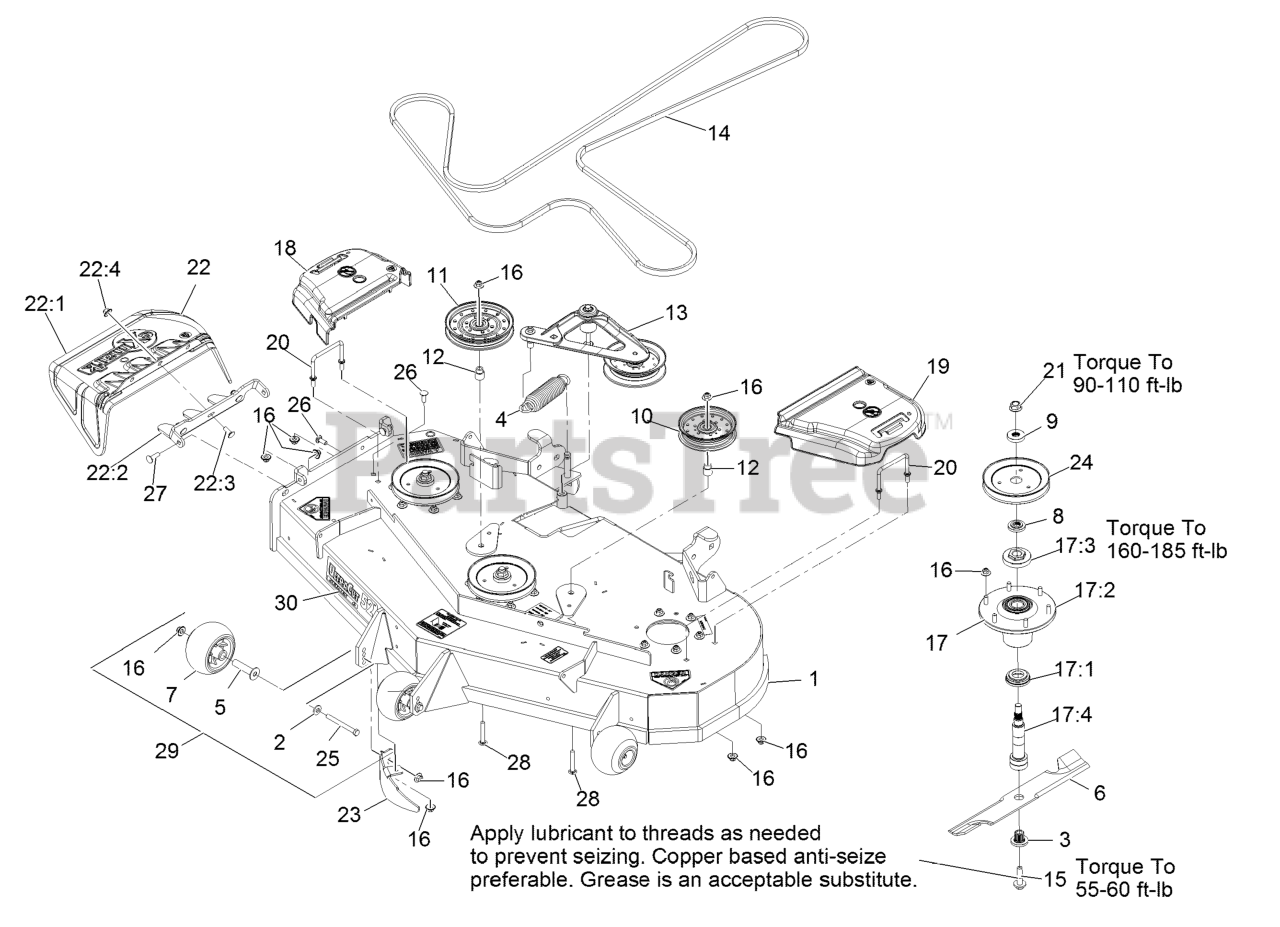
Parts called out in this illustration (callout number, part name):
1	ASM,DECK W/ DECALS 52
2	WASHER-BELLEVILLE
3	BUSHING,SPLINED
4	SPRING-EXTENSION
5	AXLE, ROLLER
7	ROLLER-SCALP, ANTI
8	SPACER,SPLINED STEPPED
9	SPACER,SPLINED
12	BUSHING-IDLER
13	DECK IDLER ASM
14	BELT,V-B X 186.00"
15	SCREW,SEMS 1/2-20 X 2.19
16	Nut-Nyloc 3/8-16 Flg
17	ASM,SPINDLE HOUSING
17:1	GUARD,BOTTOM
17:2	ASM,CUTTER HOUSING
17:3	NUT, SPINDLE 7/8-14
17:4	SPINDLE,DOUBLE SPLINE
18	COVER-BELT, RH
19	COVER-BELT, LH
20	WIREFORM-COVER
21	NUT-FLANGE, CENTERLOCK
22	ASM,DISCHARGE CHUTE
22:1	CHUTE,DISCHARGE
22:2	BRACKET,DISCHARGE CHUTE
22:3	SCREW-CARR
22:4	Nut-Nyloc 3/8-16 Flg
23	BAFFLE-DOGLEG, LZ-VT52
24	SHEAVE,BLADE DRIVE
25	SCREW-HH 3/8-16 X 3 3/4 GR 8
26	SCREW-CARR
27	Bolt-Carriage 3/8-16 X 1 1/4
28	SCREW-CARR
29	KIT, ANTI-SCALP ROLLER
30	DECAL,ULTRACUT 52 SERIES
